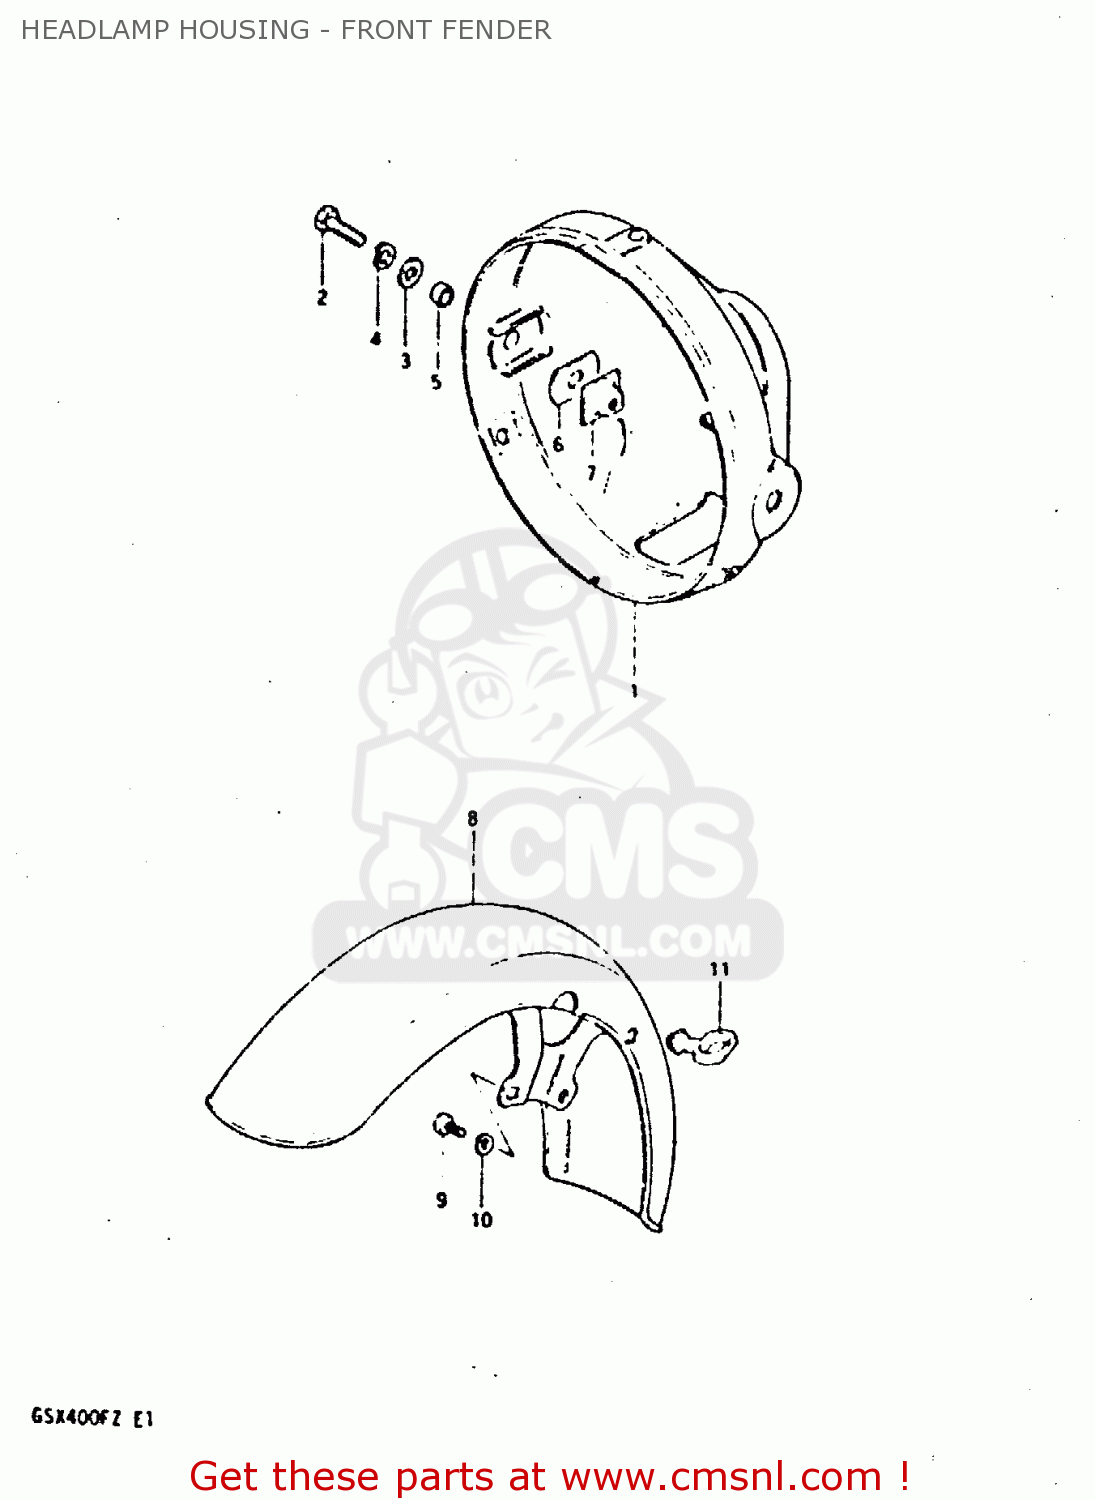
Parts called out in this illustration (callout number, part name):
1	HOUSING,HEADLAMP
2	BOLT
3	WASHER
4	LOCK WASHER
5	SPACER (8.8X12X7)
6	CUSHION
7	PLATE,HEADLAMP HOUSING
8	FENDER,FRONT
9	BOLT
10	LOCK WASHER
11	GUIDE,CABLE
